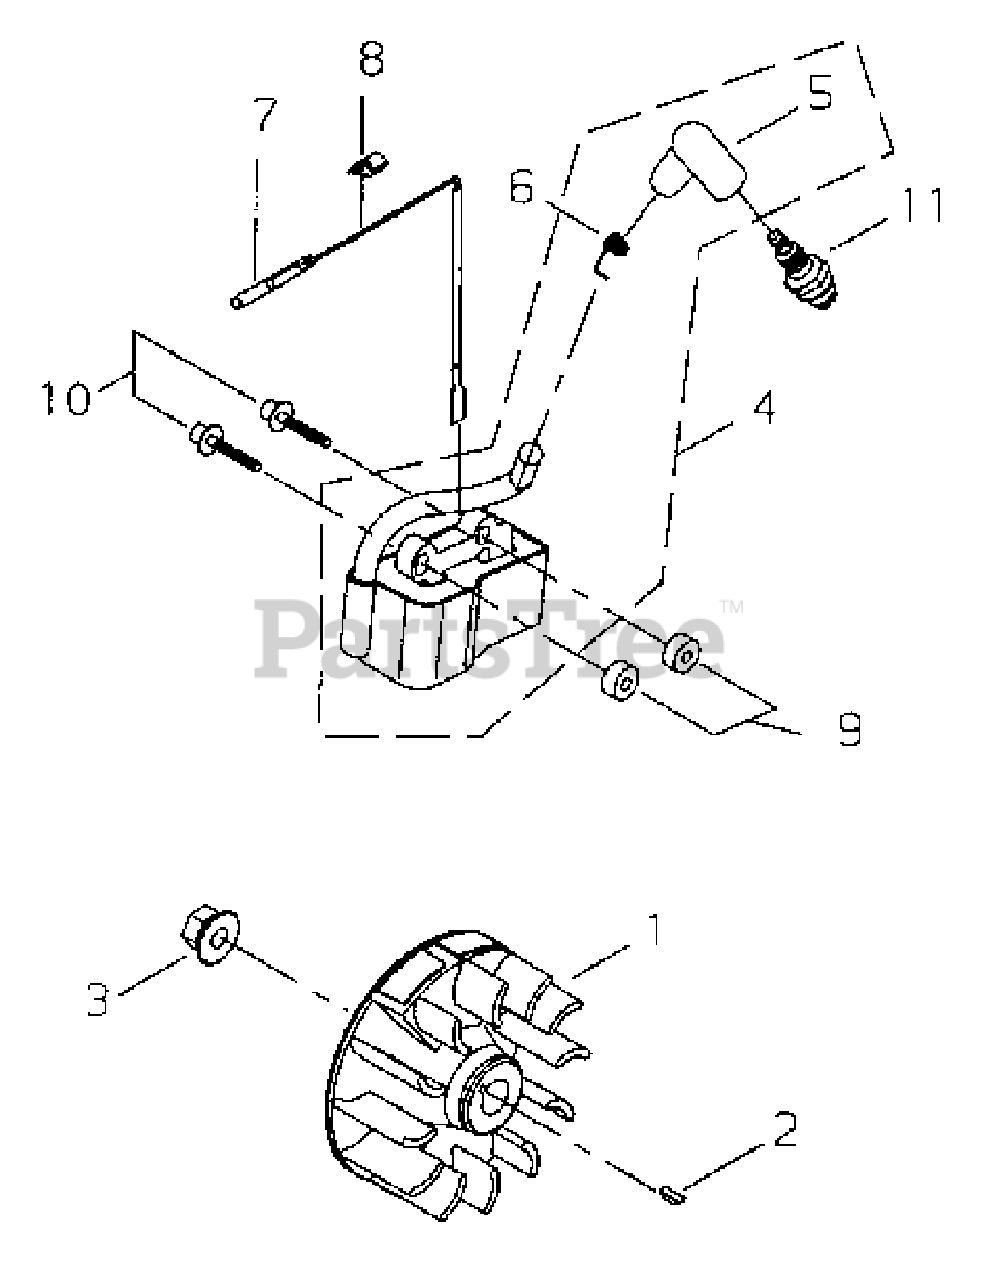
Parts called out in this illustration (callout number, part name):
1	FLYWHEEL
2	KEY - 3X10
3	NUT - 8
4	IGNITION COIL ASSY
5	CAP, SPARK PLUG
6	TERMINAL, SPARK PLUG CAP
7	LEAD - IGNITION
8	GROMMET
9	INSULATOR
10	SCREW - 4X26
11	SPARK PLUG
